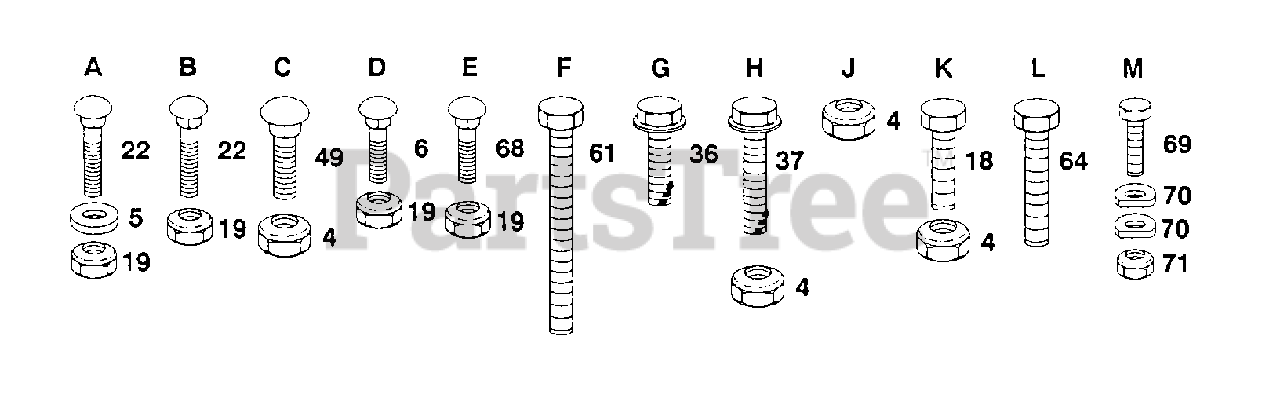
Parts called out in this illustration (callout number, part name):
5	WASHER M
6	BOLT
22	BOLT
36	SCREW
37	SCREW
49	BOLT
61	BOLT
64	BOLT.3/8-14X1.25
69	BOLT LT
70	WASHER T
